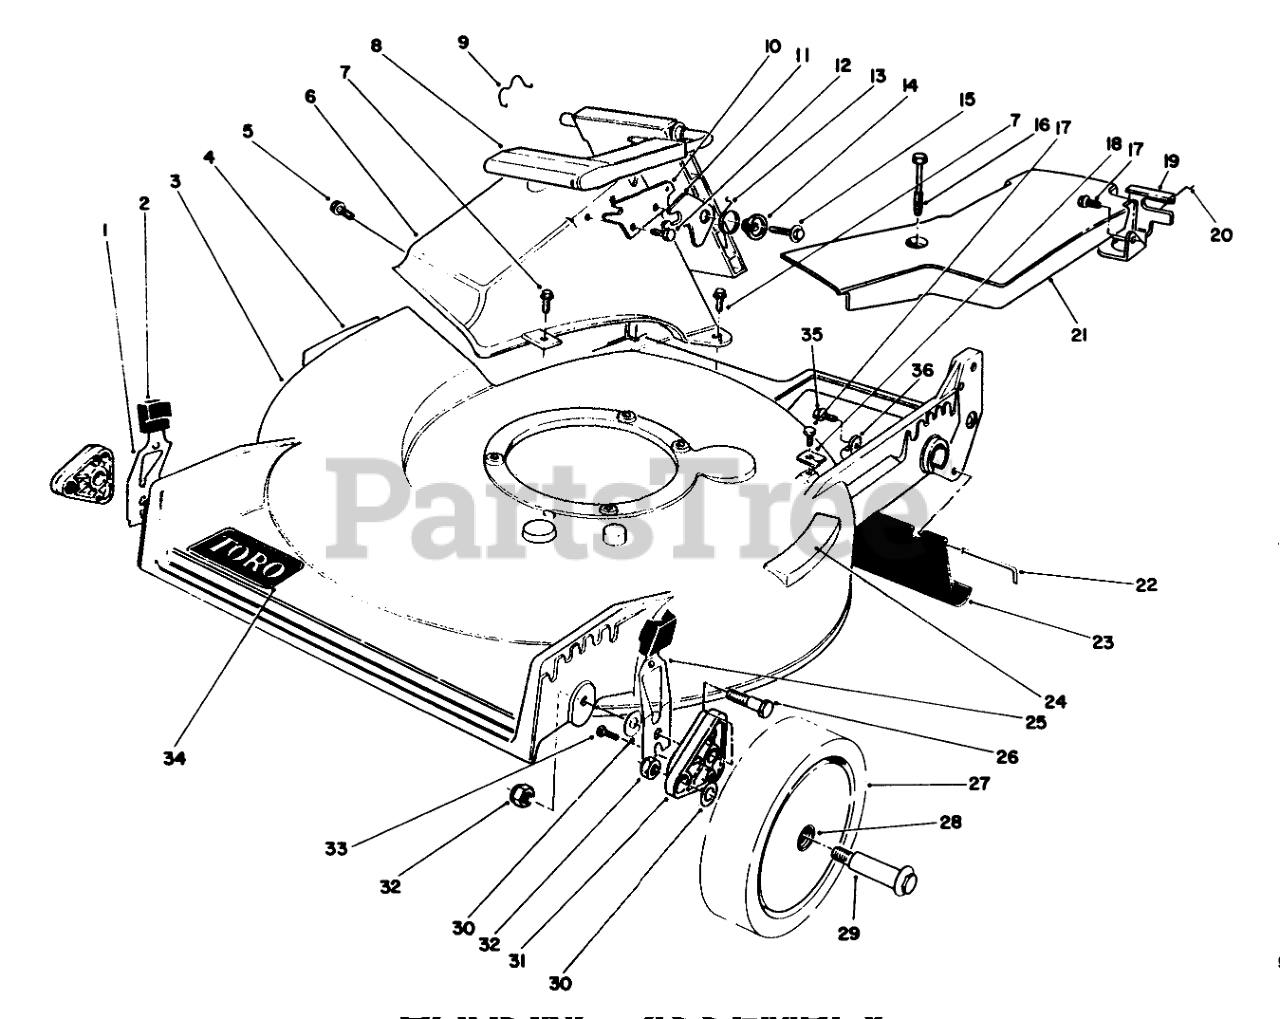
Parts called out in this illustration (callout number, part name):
1	RH SPRING ARM ASSEMBLY
2	KNOB-ARM
3	Housing (Incl. Ref. #4, 7, & 24)
4	DECAL-DANGER
5	SCREW AND WASHER ASM
6	Tunnel-Discharge
7	SCREW-HWH
8	Discharge Door Assembly
9	DOOR RET SPRING
10	DOOR LATCH PLATE
11	SAFETY LATCH
12	SCREW-PLASTITE
13	TORSION SPRING
14	DOOR SPACER
15	SCREW-HWH
16	SCREW-HHFTF
17	SCREW-HWHTF
18	CLAMP-CABLE
19	Bracket-Traction Adj.
20	RETAINER-CABLE
21	Cover-Belt
22	ROD-SHIELD
23	SHIELD-TRAILING
24	STEP PAD DECAL
25	LH SPRING ARM ASSEMBLY
26	SCREW-SHOULDER
27	Wheel & Tire Assembly (Incl. Ref. #28)
28	BUSHING
29	WHEEL BOLT
30	WASHER
31	ARM-PIVOT, FRONT
32	Nut
33	SCREW-HWH
34	DECAL
35	SCREW
36	CLAMP-CABLE
